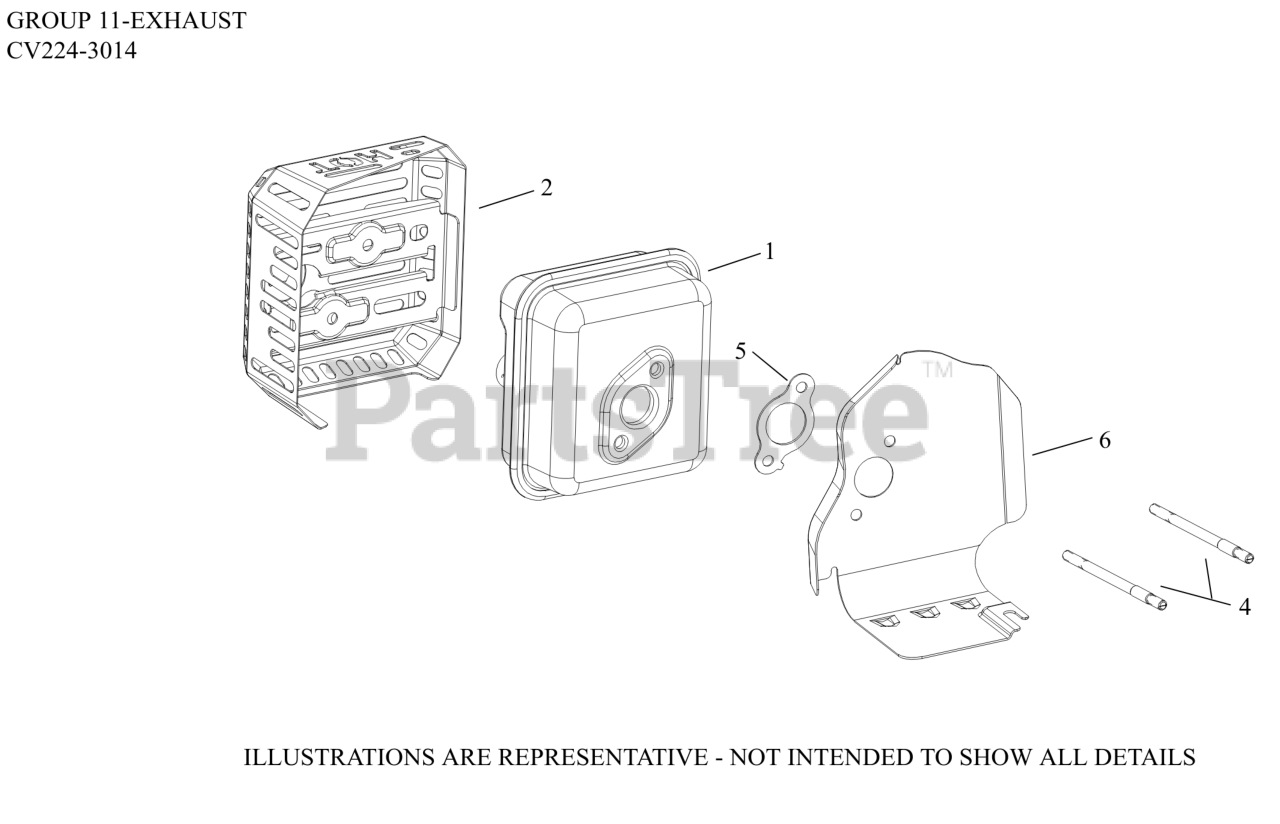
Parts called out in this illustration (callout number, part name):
1	MUFFLER, ASSEMBLY
2	GUARD, MUFFLER ASSEMBLY
4	STUD, EXHAUST (M6)
5	GASKET, MUFFLER (HEAT DEFLECTOR)
6	BAFFEL, BARREL
